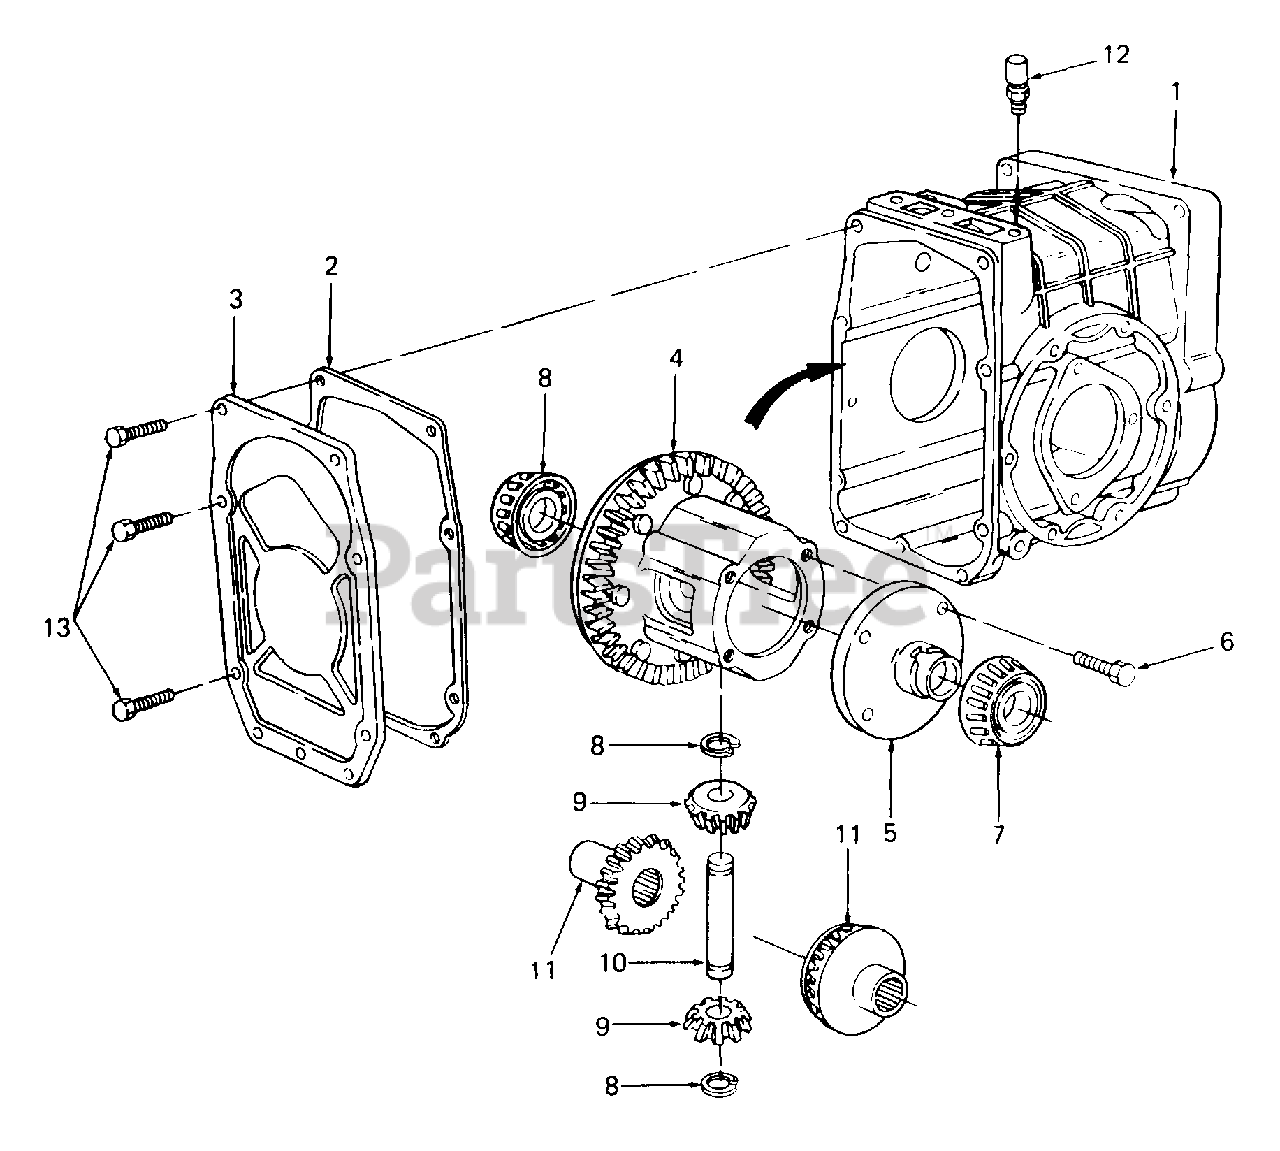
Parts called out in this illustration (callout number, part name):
1	Housing Assy, Rear Axle
2	Gasket, Rear Cover
3	Plate, Rear Cover
4	Gear Assy, Ring w/Case
5	Plate, Differential Flange
6	Bolt, Hex Patch, 5/16-18 X 1.0 Lg GR5
7	Cone, Roller Brg
8	Ring, Retaining
9	Gear, Pinion - 10T
10	Shaft, Cross
11	Gear, Side 16T
12	Breather, Housing
13	Bolt, Hex Patch, 3/8 - 16 X .62 Lg GR5
